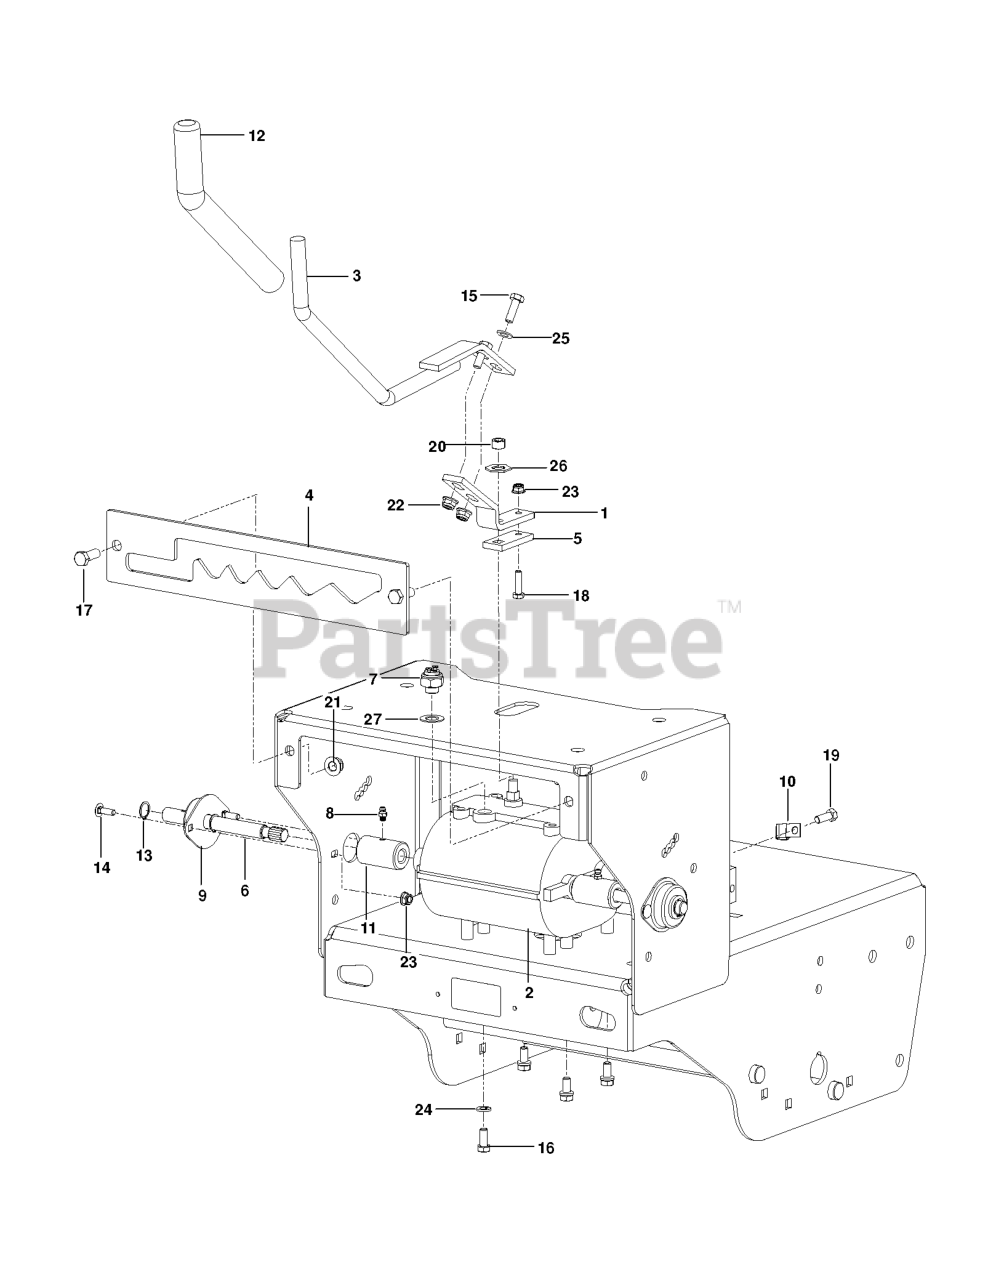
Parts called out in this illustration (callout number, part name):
1	BRACKET BRACKET, SHIFT LEVER
2	TRANSMISSION TRANSMISSION
3	LEVER SHIFT LEVER
4	PLATE PLATE, SHIFT LEVER DETEN
5	PLATE PLATE, SHIFT
6	SHAFT SHAFT, HALF
7	SWITCH SWITCH-NEUTRAL START N.
8	FITTING FITTING, 1/4-28 STRGT
9	BEARING BRG-FLG .625 X 1.875 X
10	CLIP P-CLIP, .500 INSULATED
11	COUPLER COUPLER
12	GRIP GRIP, HANDLE
13	RING RG-RTNG-E X T .579 X .035
14	BOLT BOLT RDHDSQNK .25-20 X .7
15	BOLT BOLT HEX .31-18 X 1.00 GR
16	BOLT BOLT HEX .31-18 X .75 GR5
17	BOLT BOLT HEX .38-16 X 1.00 GR
18	BOLT BOLT HEX .25-20 X 1.00 GR
19	BOLT BOLT HEX .38-16 X .75 GR5
20	NUT NUT, LK-CTR .375-24 YWZC
23	NUT NUT, LK-NYL-FLG .25-20 YWZ
24	WASHER WASHER, LK .31 X .078 R
25	WASHER WASHER, FL-STL .344 X .
26	WASHER WASHER, LK .375 X .130
27	WASHER WASHER, FL-STL, .563 X
